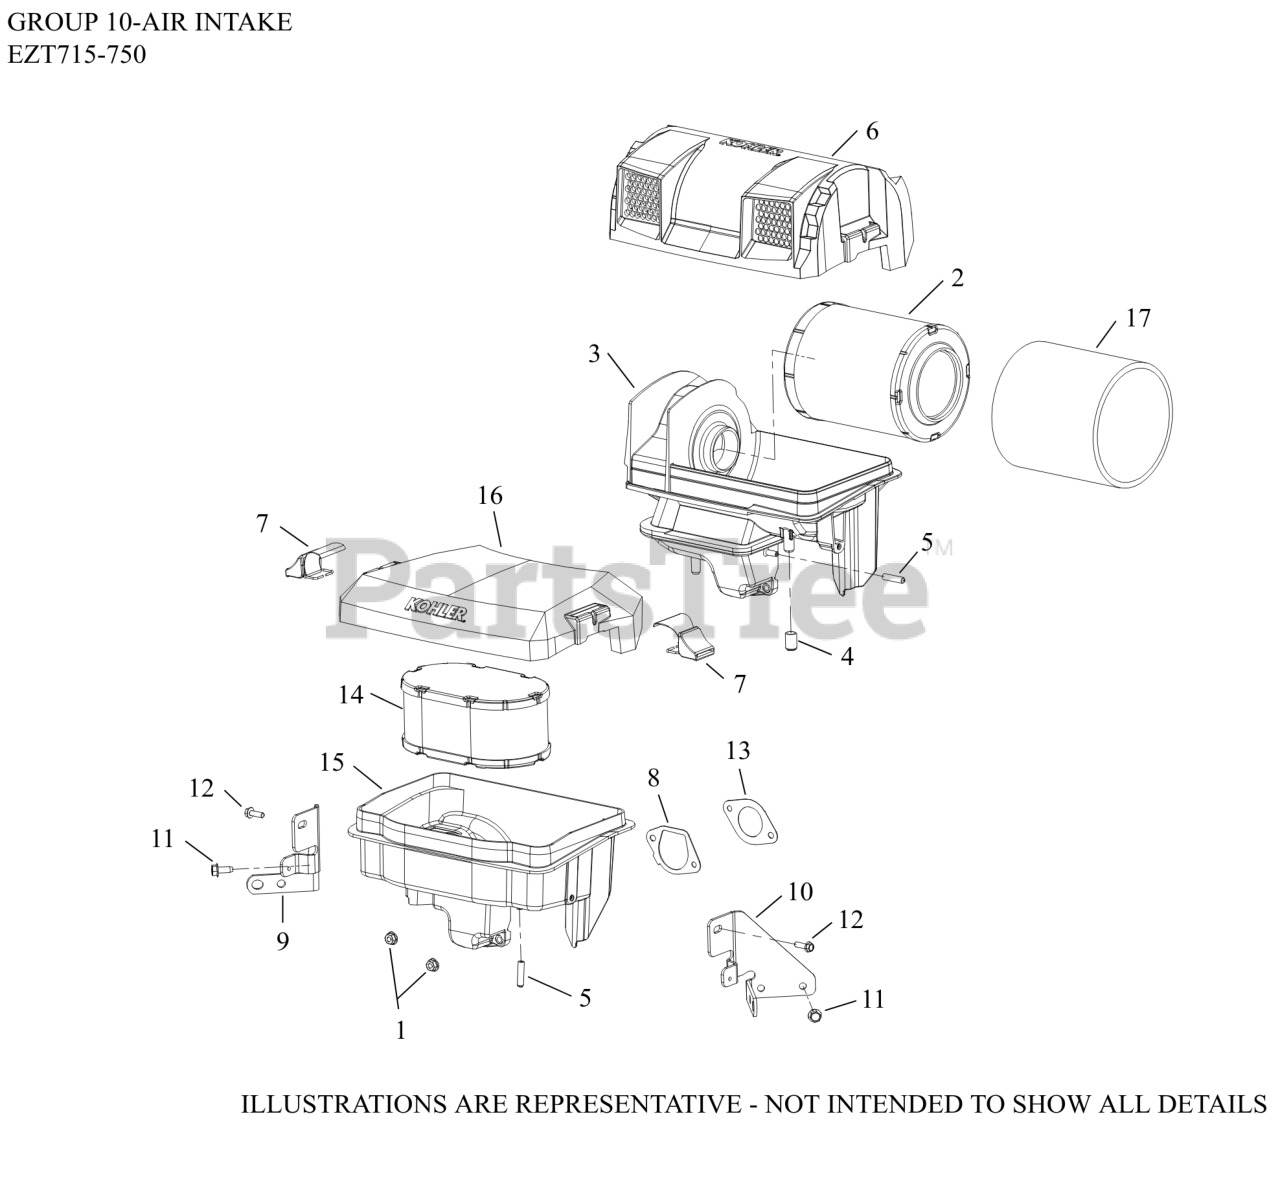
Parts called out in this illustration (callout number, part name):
1	NUT, FLG M6X1.0
2	ELEMENT, AIR FILTER
3	BASE ASSEMBLY, AIR CLEANER (HDAC)
4	CAP, MASKING
5	CAP, MASKING
6	COVER, AIR CLEANER (HDAC)
7	LATCH ASSY, AIR CLEANER COVER
8	GASKET, AIR CLEANER BASE
9	BRACKET, AIR CLEANER BASE (#1 SIDE)
10	BRACKET, AIR CLEANER BASE (#2 SIDE)
11	SCREW, THREAD FORMING
12	SCREW, HI-LOW
13	GASKET, THROTTLE BODY
